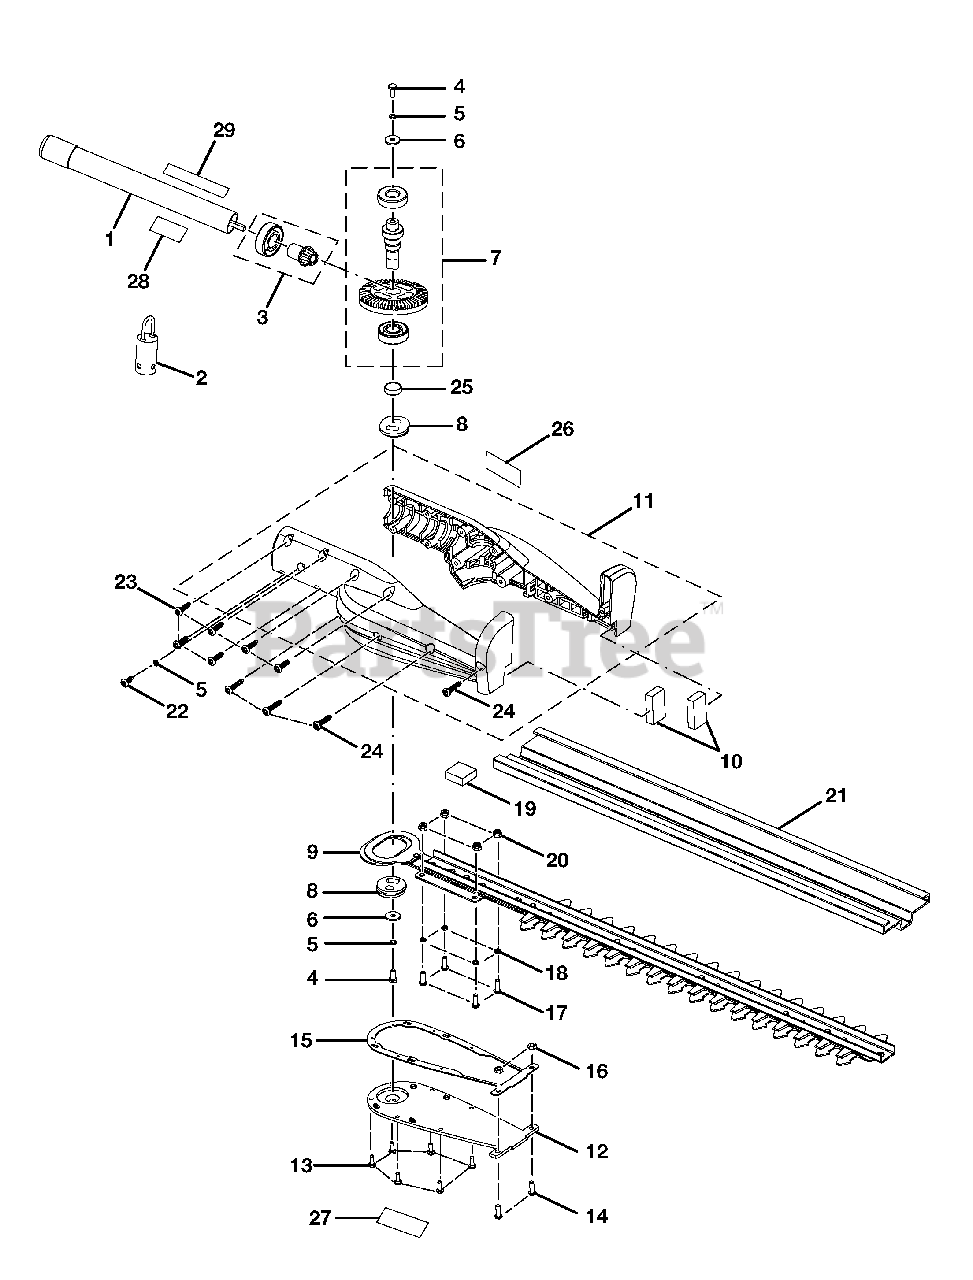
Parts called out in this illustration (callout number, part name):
1	LOWER DRIVE SHAFT ASSEMBLY
2	HANGER CAP
3	PINION ASSEMBLY
4	SCREW (M5 X 10 mm)
5	SPRING WASHER
6	FLAT WASHER
7	OUTPUT SHAFT ASSEMBLY
9	BLADEASSEMBLY
11	HOUSINGASSEMBLY
12	HOUSING BOTTOM PLATE
13	SCREW (M3.5 X 8 mm)
14	SCREW (M4 X 12 mm)
16	NUT (M4)
17	SCREW (M4 X 16 mm)
18	SPRING WASHER
20	NUT (M4)
21	BLADE GUARD (SCABBARD)
22	SCREW (M4.8 X 7 mm)
23	SCREW (M4.8 X 15 mm)
24	SCREW (M4.8 X 26 mm)
26	EXPAND-IT LOGO LABEL
27	HOT SURFACE LABEL
29	WARNING LABEL
